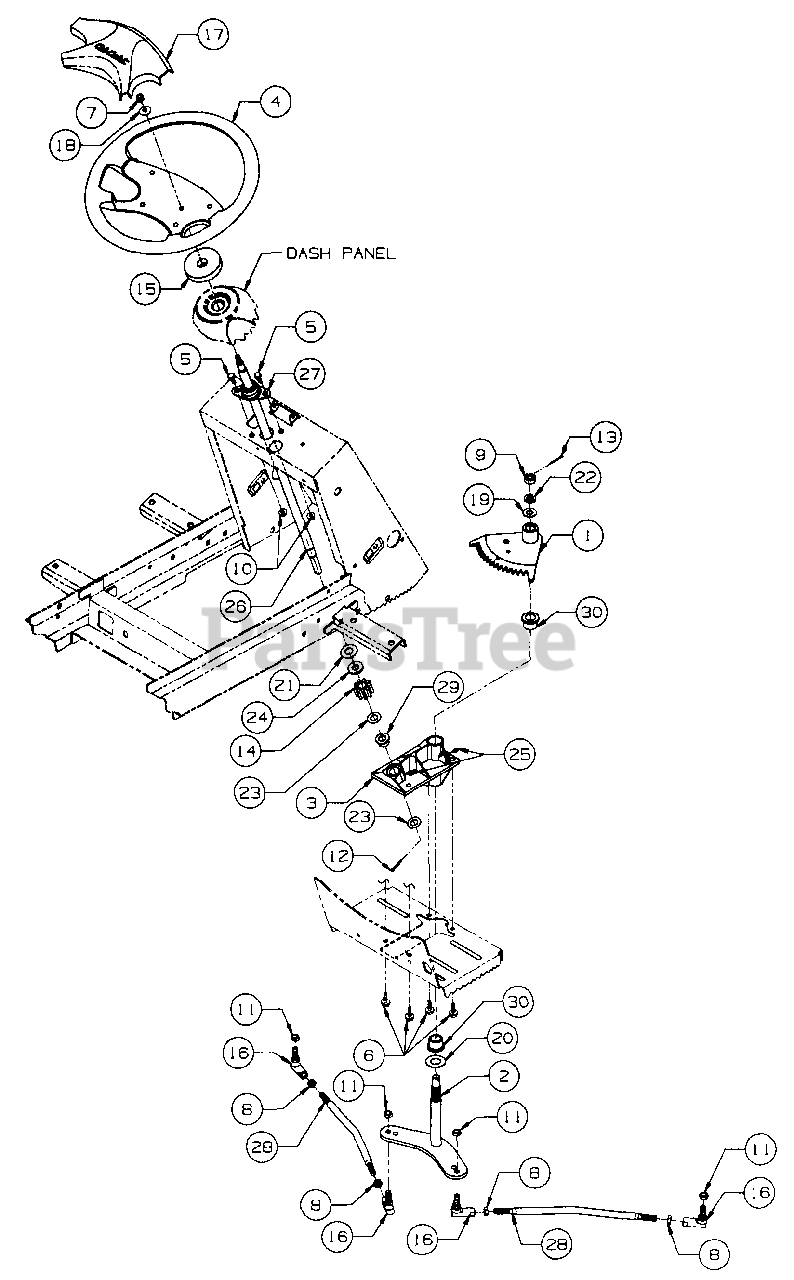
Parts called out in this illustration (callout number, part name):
1	Segment Assy, 18T - Steering
2	Arm Assy, Lower Steering
3	Housing Assy, Steering
4	Wheel, Steering
5	Screw, Hex Cap, 1/4-20 x .62 Lg
6	Screw, Hex Wash Sf-Tapp 5/16-18 x .75 Lg
7	Nut, Hex Center Lock, 5/16-24
8	Nut, Hex Jam, 3/8-24 GR5
9	Nut, Hex Slotted, 1/2-20 GR5
10	Nut, Hex Flange Lock, 1/4-20
11	Nut, Hex Lock, 3/8-24 GR5
12	Pin, Cotter, 1/8 Dia x 1.0 Lg
13	Pin, Cotter, 3/32 Dia x 1.25 Lg
14	Pinion, Steering
15	Gasket, Steering
16	Joint, Ball, 3/8-24
17	Insert, Steering Wheel, Cub Cadet
18	Washer, Bell, .340 x .88 x .06 Thk
19	Washer, Flat, .510 x 1.0 x .06 Thk
20	Washer, Flat, .760 x 1.50 x .030 Thk
21	Washer, Flat, .56 x 1.0 x .040 Thk
22	Washer, Lock, 1/2
23	Washer, Flat, .531 x 1.0 x .027 Thk
24	Washer, Rubber Flat, .50 x 1.12 x .125 Thk
25	Fitting, Lube, 3/16 Drive Type
26	Shaft, Steering
27	Bearing, Flange
29	Bearing, Flange, .503 ID
30	Bearing, Bronze Flange, .75 ID
